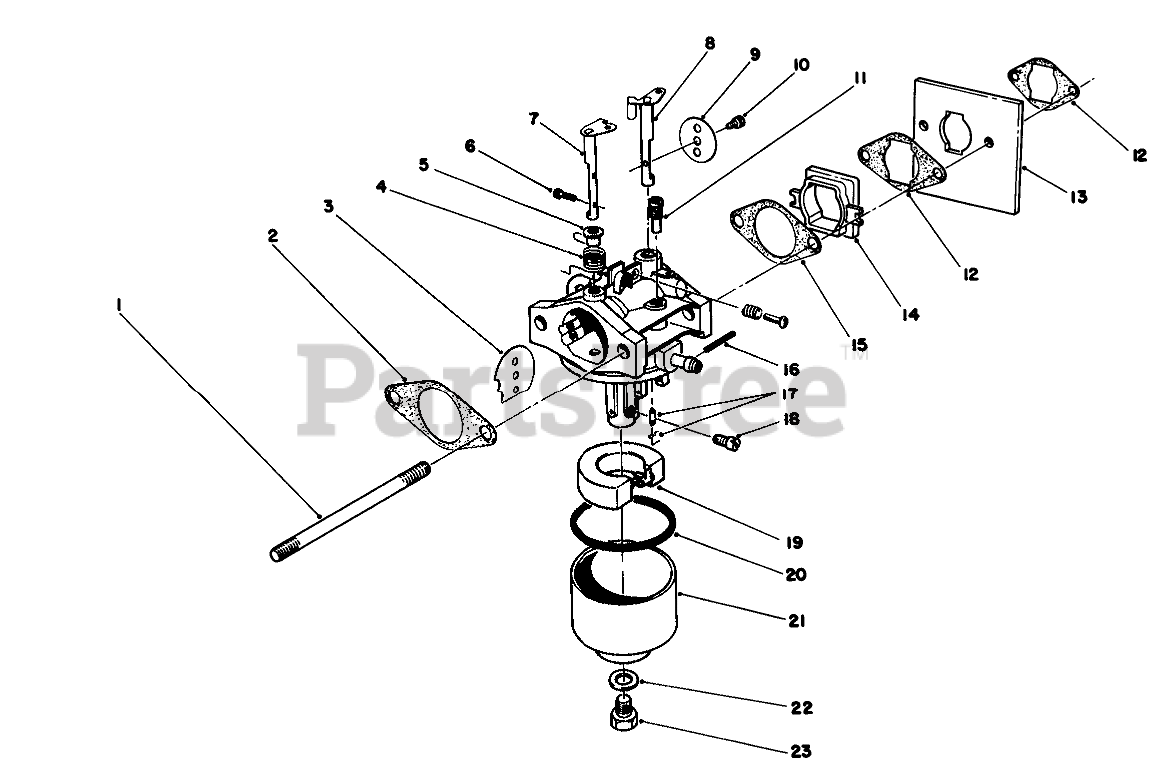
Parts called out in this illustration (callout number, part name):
1	CARB STUD BOLT
2	GASKET-AIR CLEANER
3	PLATE
3	CHOKE VALVE
4	SPRING
5	BUSHING
6	SCREW
7	SHAFT-CHOKE
8	SHAFT
9	PLATE
10	Screw-Throttle
11	PILOT JET
12	GASKET
13	SHIELD
14	INSULATOR
15	Clamp
16	Pin
17	NEEDLE VALVE ASM
17	NEEDLE
18	MAIN JET (76.3)
19	FLOAT
20	GASKET
21	Bowl-Float
22	GASKET
23	Bolt
